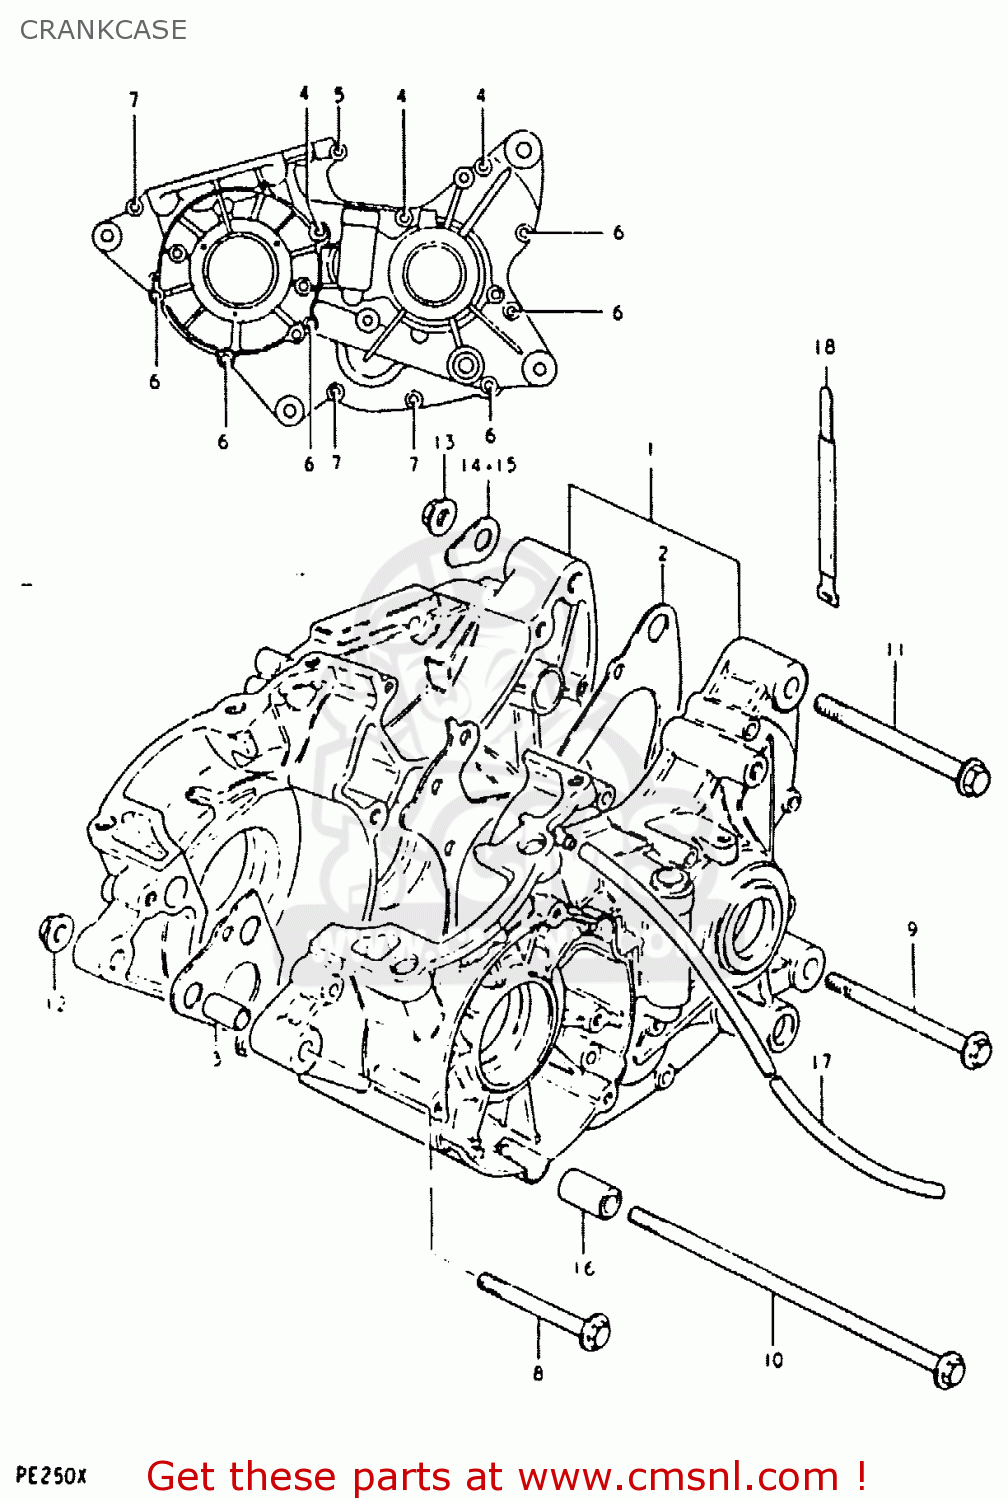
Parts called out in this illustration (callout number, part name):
1	CRANKCASE SET
2	GASKET,CRANKCASE (MCA)
3	PIN
4	SCREW 6X65
5	SCREW
6	SCREW
7	SCREW (6X35)
8	BOLT(8X67)
9	BOLT
10	BOLT
11	BOLT
12	NUT
13	NUT
14	WASHER
15	WASHER
16	SPACER(8.6X16X26)
17	HOSE
18	CLAMP L:110
